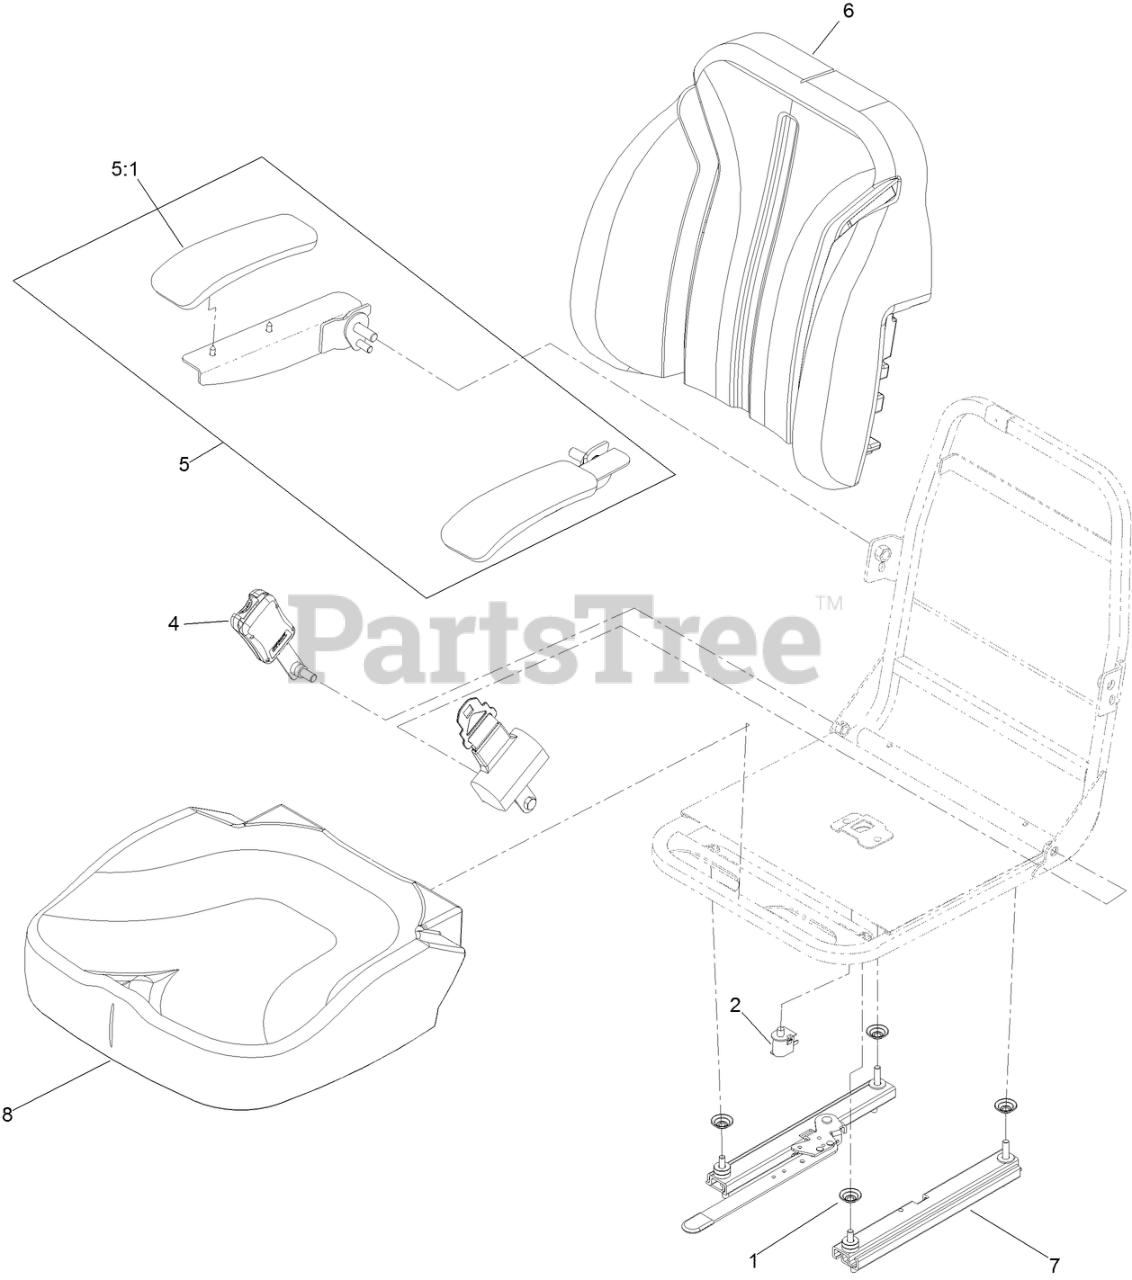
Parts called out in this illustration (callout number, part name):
1	SPACER-MOUNTING
2	SWITCH-BAIL
4	SEAT BELT KIT
5	ARMREST KIT
5:1	CUSHION-REST, ARM
6	COVER-BACK, TORO SEAT
7	TRACK-SEAT
8	COVER-BOTTOM, TORO SEAT
